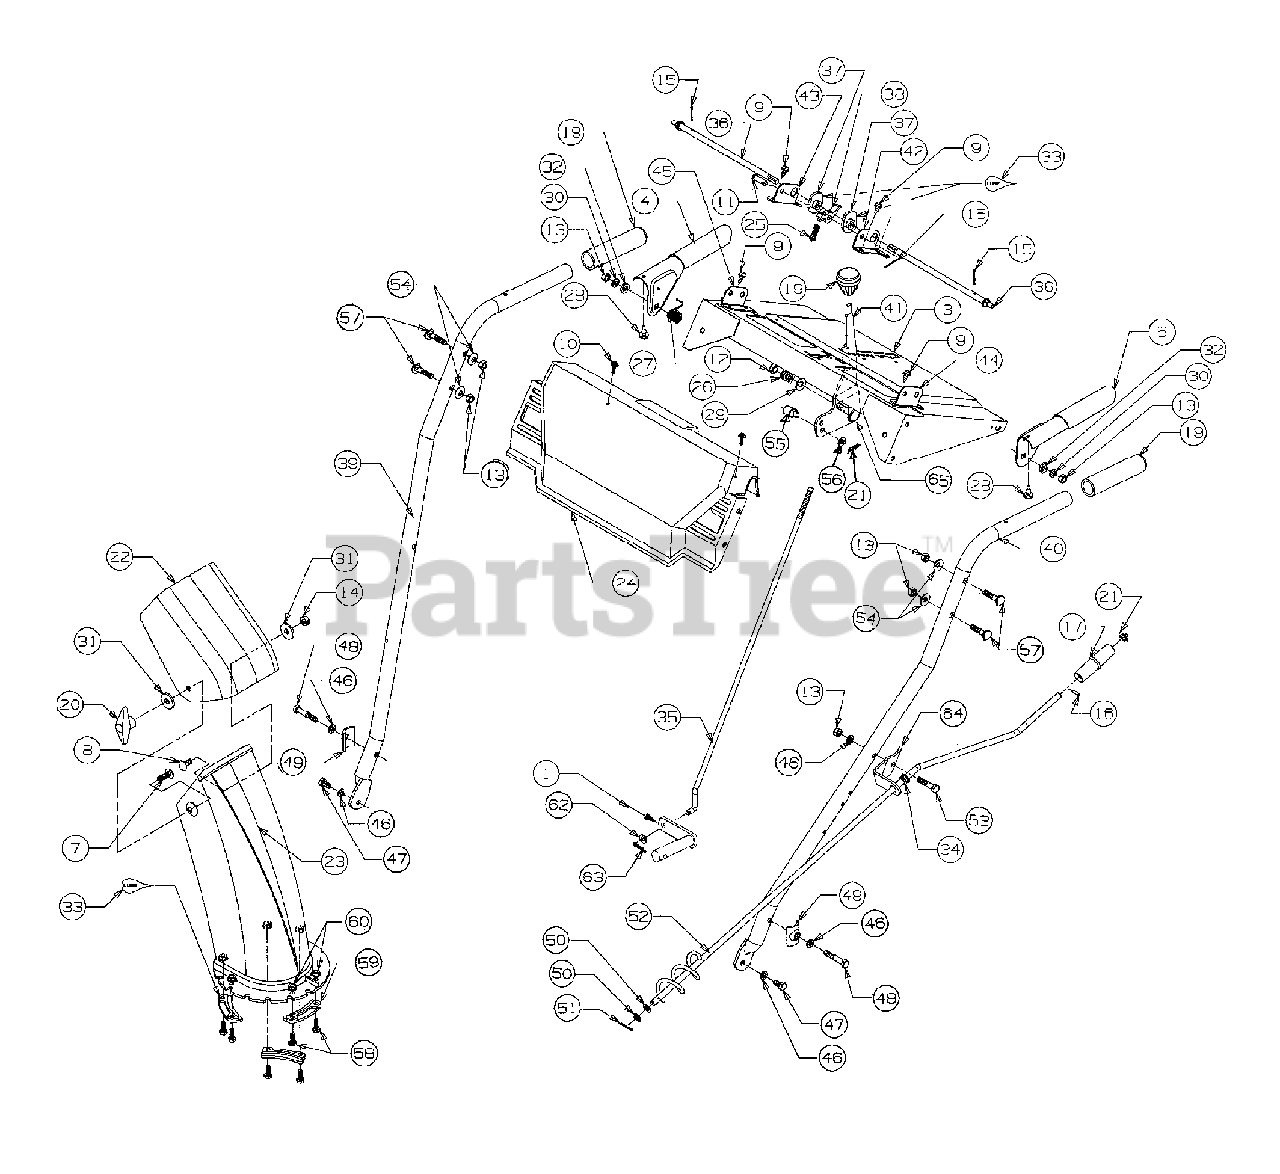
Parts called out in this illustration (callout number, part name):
5	Handle - Engagement - L.H.
7	Screw
8	Bolt-Carriage
9	Screw
10	Screw
11	Pin - Clevis
12	Nut - Hex
13	Nut - Hex
14	Nut - Lock
15	Pin - Cotter
16	Pin - Roll
18	Knob - Shift
21	Cap - Push
22	Chute - Upper
23	Chute - Lower
24	Panel - Handle
25	Spring
26	Spring
27	Spring
28	Bumper
29	Washer - Bell
30	Washer - Lock
31	Washer
32	Washer
33	Lubricant
34	Bushing - Plastic
35	Rod - Shift
36	Rod - Cam
37	Cam - Handle Lock
38	Pawl - Handle Lock
46	Washer - Lock
47	Screw
48	Screw
49	Tab - Handle
50	Washer - Flat
51	Pin - Cotter
52	Crank - Chute
53	Screw
54	Washer - Bell
55	Ferrule
56	Washer - Flat
57	Bolt - Carriage
58	Screw
59	Keeper - Chute Flange
60	Nut - Lock
62	Washer - Flat
63	Pin - Cotter
